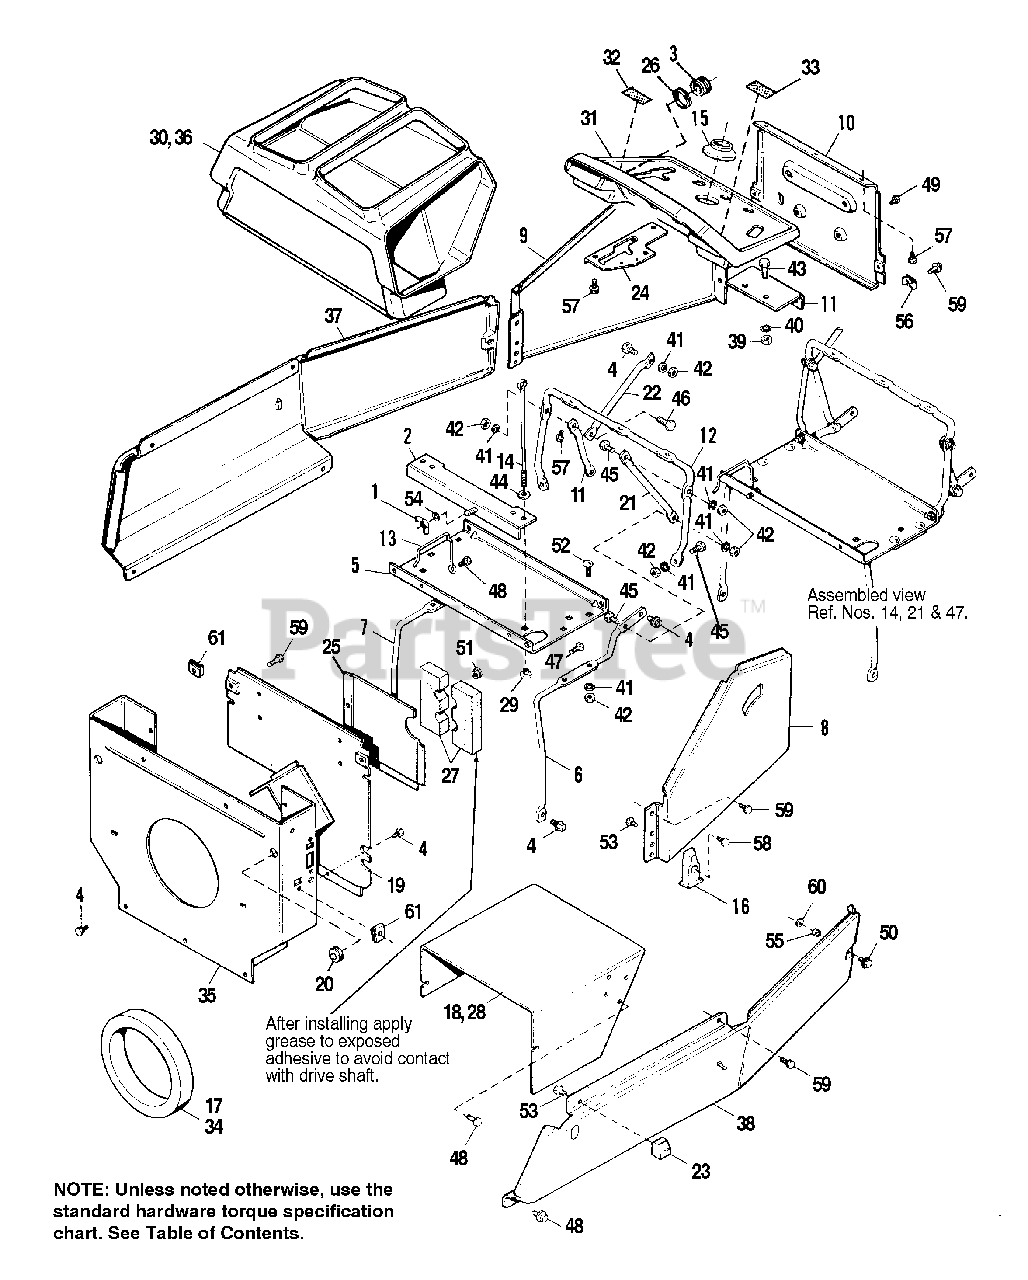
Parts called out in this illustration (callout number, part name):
1	NUT, Wing, 1/4-20
2	HOLD DOWN, Battery
4	SCREW, Hex, Taptite, 5/16-18 x 3/4
5	TRAY, Battery
6	SUPPORT, Battery Tray, LH
7	SUPPORT, Battery Tray, RH
8	DASH PANEL, Upper, LH
9	DASH PANEL, Upper, RH
10	PANEL, Rear Dash
11	BRACKET, Mounting, Dash Panel, Rear
12	SUPPORT, Dash Cap
13	GUIDE, Plenum
14	ROD, Battery Hold Down
15	BOOT, Steering Stem
16	GUIDE, Spacer, Hood
17	SEAL, Engine, Bulkhead
18	COVER, Tunnel
19	PANEL ASSY., Bulkhead
20	GROMMET, 1/2 I.D.
21	BRACE, Dash Cap Support, LH
22	BRACE, Dash Cap Support, RH
23	SPACER, Hood/Side Panel
24	PLATE, Speed Control Lever
25	PANEL, Clean Out
26	RING, Retaining
27	SEAL, Drive Shaft
28	COVER, Tunnel
29	NUT, Plastic, 1/4-20
30	PLENUM, Air Induction
31	CAP, Dash
32	DECAL, Indicator, Right
33	DECAL, Indicator, Left
34	SEAL, Engine, Bulkhead
36	PLENUM, Air Induction
37	LOWER PANEL ASSY., RH
38	LOWER PANEL ASSY., LH
39	NUT, Hex, 3/8-16
40	LOCKWASHER, 3/8
41	LOCKWASHER, 5/16
42	NUT, Hex, 5/16-18
43	CAPSCREW, Hex Hd., 3/8-16 x 1
44	WASHER, Plain, 1/4 x 5/8 x 3/64
45	CAPSCREW, Hex Hd., 5/16-18 x 3/4
46	CAPSCREW, Hex, 5/16-18 x 1-1/4
47	CAPSCREW, Hex Hd., 1/4-20 x 3/4
48	SCREW, Hex, Taptite, 1/4-20 x 1/2
49	SCREW, Hex, Taptite, 1/4-20 x 5/8
50	SCREW, Hex, Taptite, 1/4-20 x 1
51	NUT, Hex, Flange, Whizlock, 1/4-20
52	CARRIAGE BOLT, 5/16-18 x 7/8
53	SCREW, Hex, Plastite, #10-14 x 1/2
54	WASHER, 1/4
55	SPACER, Side Panel
56	SPEED NUT, "J" Type, 14A
57	SCREW, Hex, Plastite, 1/4-10 x 5/8
58	SCREW, Hex, Washer Hd., 1/4 x 1
59	SCREW, Hex, Type "AB" , 1/4-14 x 5/8
60	PUSHNUT, 1/4
61	SPEED NUT, "U" Type, 14A
